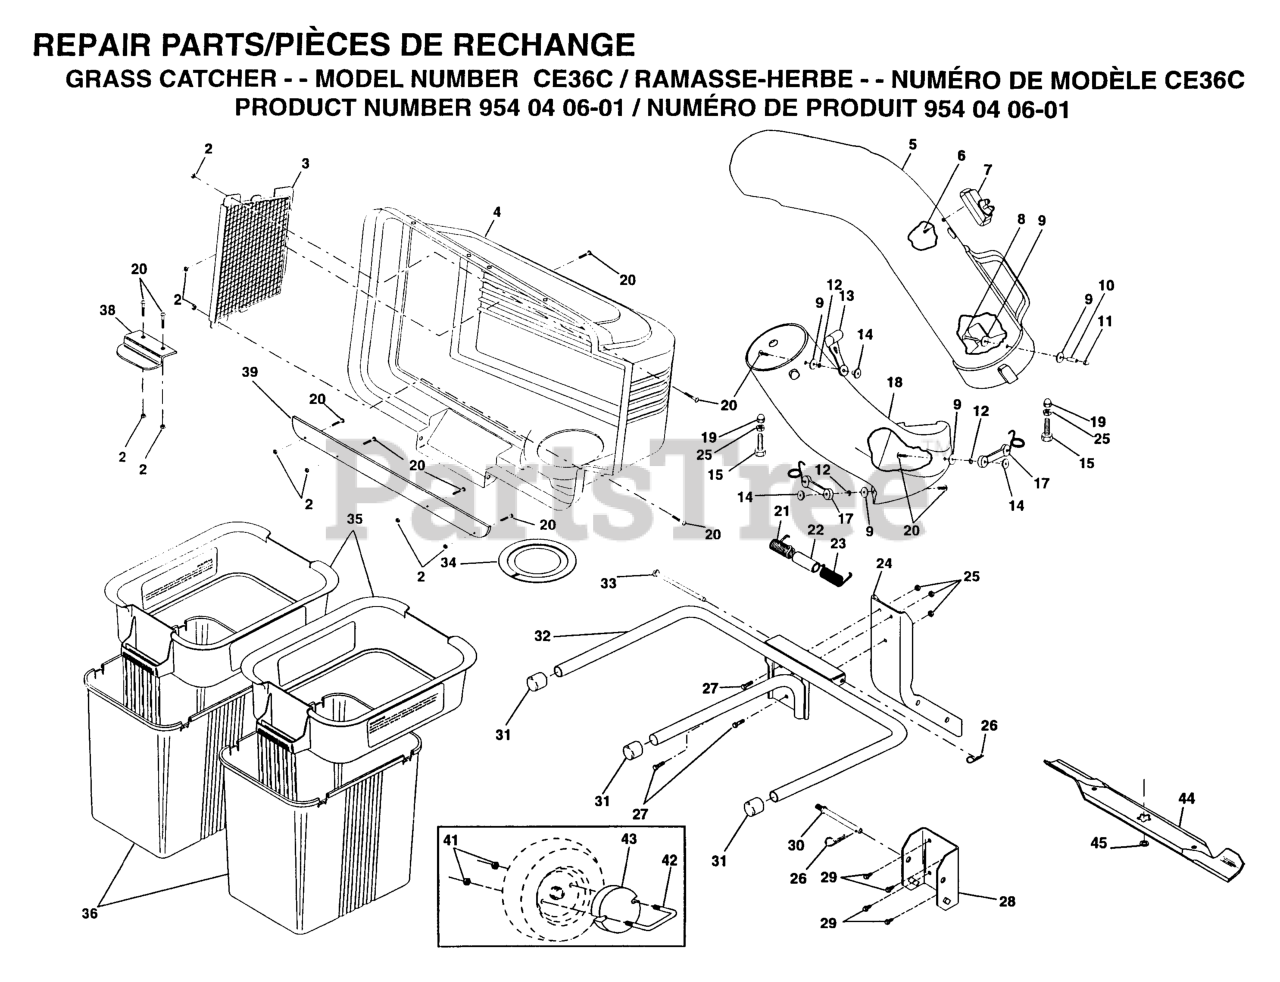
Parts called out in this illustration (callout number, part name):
3	COVER SCREEN
4	COVER
5	CHUTE.UPPER.BAGGER.36"
7	INDICATOR DUMP BAG
8	SCREW
11	NUT
12	LOCKWASHER #10
13	LATCH.HOOD.
14	WELDNUT
15	BOLT GT
17	LATCH ASSEMBLY
18	CHUTE LOWER 36"
20	SCREW
21	SPRING COVER LH
22	SPACER.COVER.BAGGER
23	SPRING COVER RH
24	SUPPORT POST
25	LOCKNUT
26	RETAINER-SPRNG RB
27	BOLT
28	MTG BRACKET
29	Screw 5/16-18 x 1/2 Hex, Self Tapping 5/16-18 x 1/2
30	SUPPORT POST PIN
31	TUBING PLUG
32	BAGGER FRAME
33	HINGE PIN
34	GASKET.COVER.BAGGER
35	CONTAINER TOP
36	CONTAINER BOTTOM
38	LATCH CER38
39	STRIP.REINFORCE.BAGGER.2BIN.BL
41	NUT
43	WEIGHT, FRT WHEEL
